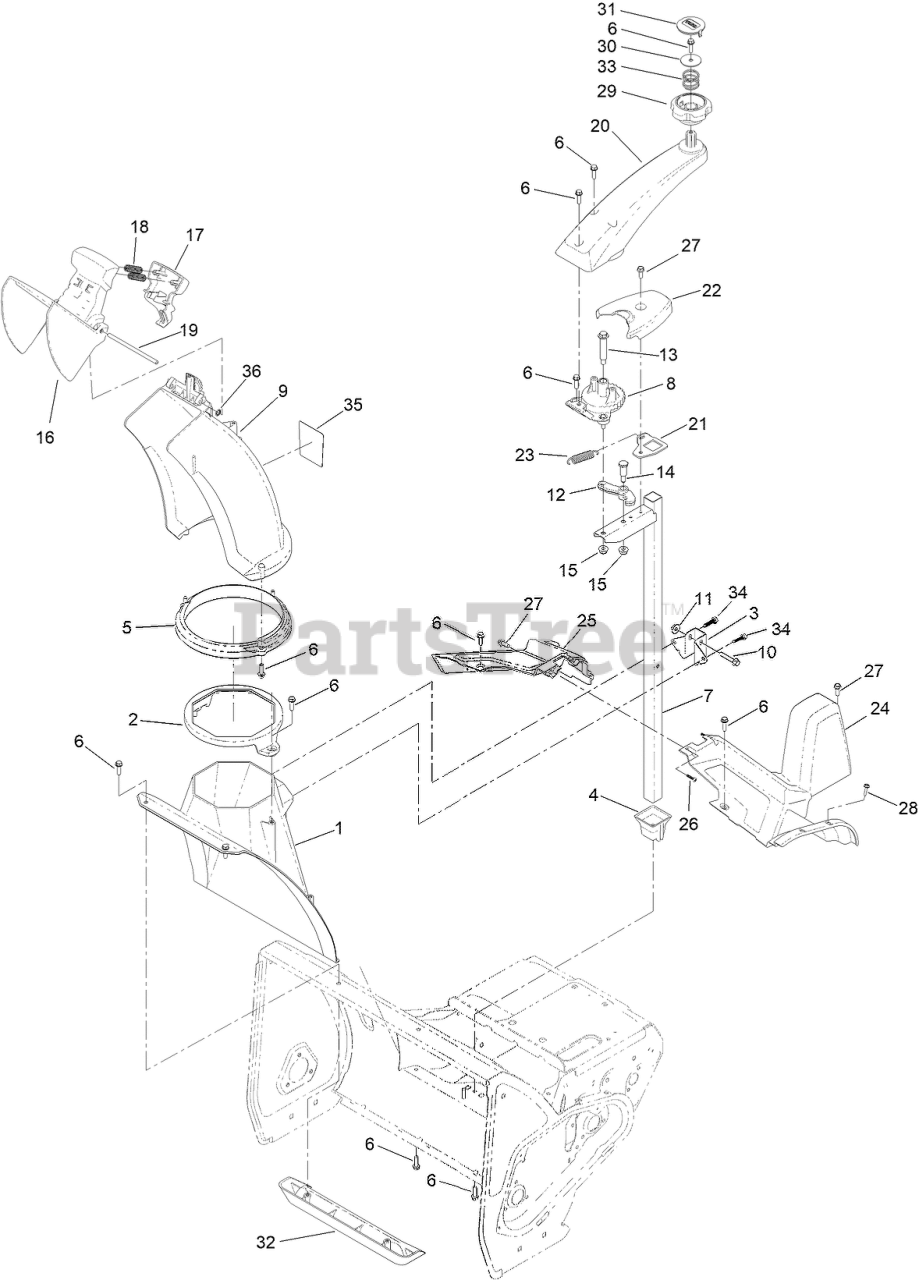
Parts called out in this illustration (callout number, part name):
1	CHUTE-LOWER
2	GUIDE-CHUTE
3	BRACKET-POST, SUPPORT (CHUTE)
4	RETAINER- POST, CHUTE
5	RING-CHUTE
6	SCREW-PLASTITE, HWH
7	POST-CHUTE, MANUAL
8	GEAR-CHUTE, MANUAL
9	CHUTE-DISCHARGE
10	SCREW-HHF
11	NUT-HF
12	LATCH-CHUTE
13	BOLT-SHOULDER
14	SCREW-SHOULDER, HH
15	NUT-HF
16	DEFLECTOR-CHUTE
17	TRIGGER-DEFLECTOR
18	SPRING-COMPRESSION
20	HANDLE-CHUTE, MANUAL
21	BKT-SPRING SUPPORT
22	COVER-SPRING
23	SPRING-EXTENSION
24	SHROUD-UPPER, LH
25	SHROUD-LOWER, RH
26	SCREW-PPH
27	SCREW-HWH
28	SCREW-PLASTITE, HWH
29	KNOB-CONTROL, CHUTE
30	WASHER-FENDER
31	INSERT-KNOB
32	KICKER-HOUSING
33	SPRING-COMPRESSION
34	SCREW-FLANGE, PLASTIC
36	RING-RETAINING
